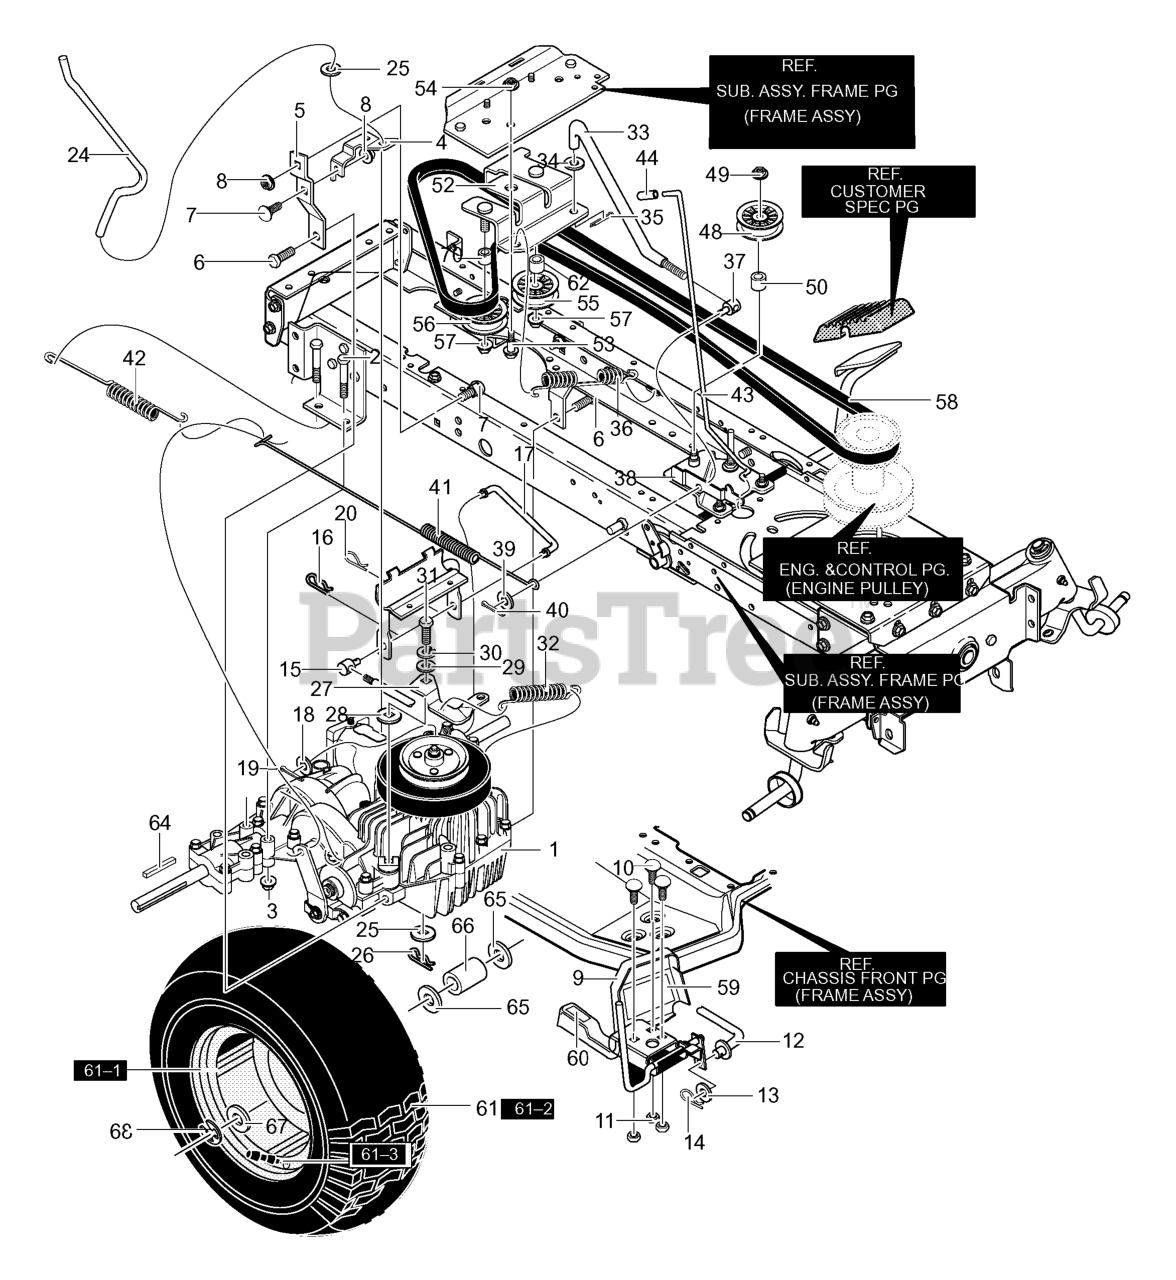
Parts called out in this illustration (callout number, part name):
1	Transaxle, VST205 **
2	Screw, 5/16-18 x 2.50
3	Nut, 5/16-18 Wdfllk
4	Bracket, Disconnect
5	Torque Strap
6	Screw, 5/16-18 x 0.75
7	Bolt, 5/16-18x.63
8	Nut, 5/16-18 Hexwdfllk Wh
9	Pedal Assy., Hydro
10	Bolt, 5/16-18x.75
11	Nut, 5/16-18
12	Rod, Pedal Link
13	Washer
14	Hair Pin
15	Adjust Nut 1/2-13
16	Hair Pin
17	Rod Hydro Link
18	Flat washer
19	Cotter Pin
20	Hair Pin
24	Rod, Disconnect
25	Washer, Flat
26	Pin, Cotter
27	Arm Disconnect
29	Flat washer
30	Washer
31	Screw, 1/4-28x.75
32	Spring, Extension
33	Rod, Clutch
34	Flat washer
35	Cotter Pin
36	Spring, Clutch
37	Nut, Adjusting
38	Latch, Park Brake
39	Flat washer
40	Cotter Pin
41	Spring, Extension
42	Spring, Tension
43	Park Brake Rod
48	Pulley, Idler
49	Nut, 3/8-16
50	Spacer, 1/2 to 17MM
52	Asm., Bracket Idler
53	Bolt, 3/8-16
54	Nut, 3/8-16
55	Pulley, Idler
56	Pulley, Idler
57	Nut, 3/8-16
58	Belt, Motion Drive
60	Pad, Toe Sandpaper
61	Tire & Rim
61-1	Valve Stem
62	Spacer 1/2 to 17MM
64	Key, Square
65	Flat washer
66	Spacer .87x1.78
67	Flat washer
68	Ring, E
70	Spacer 1/2 to 17MM
